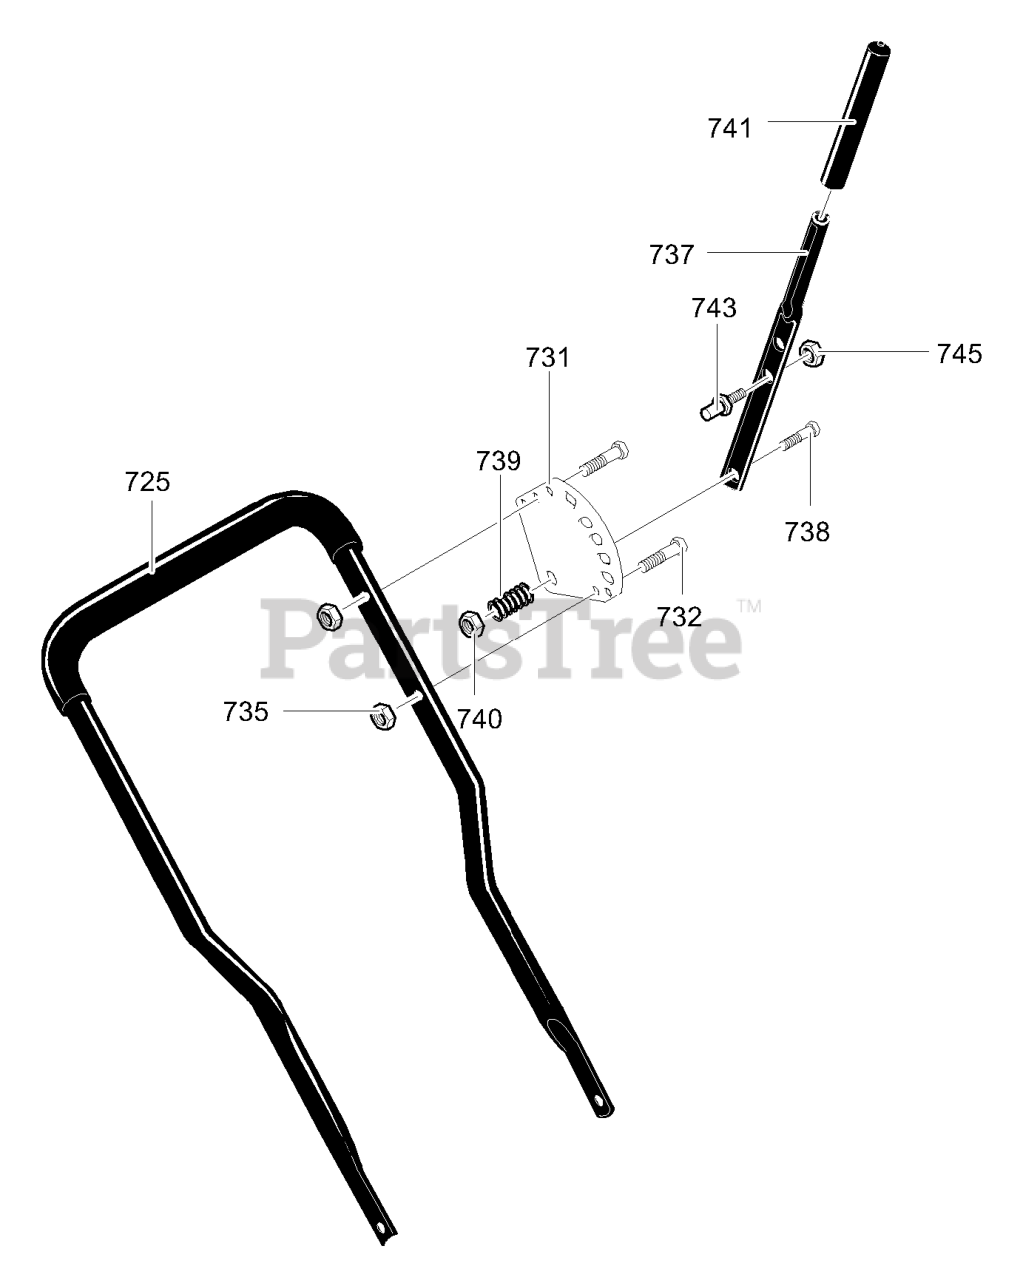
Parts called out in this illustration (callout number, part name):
725	Upper Handle & Foam
731	Selector Plate
732	Screw, 1/4-20x1.25
735	Nut, 1/4-20
737	Depth Adjust Handle
738	Screw, 5/16-18 x 1.25
739	Spring, Compression
740	Nut, 5/16-18
741	Grip, Hand
745	Nut, 3/8-16
